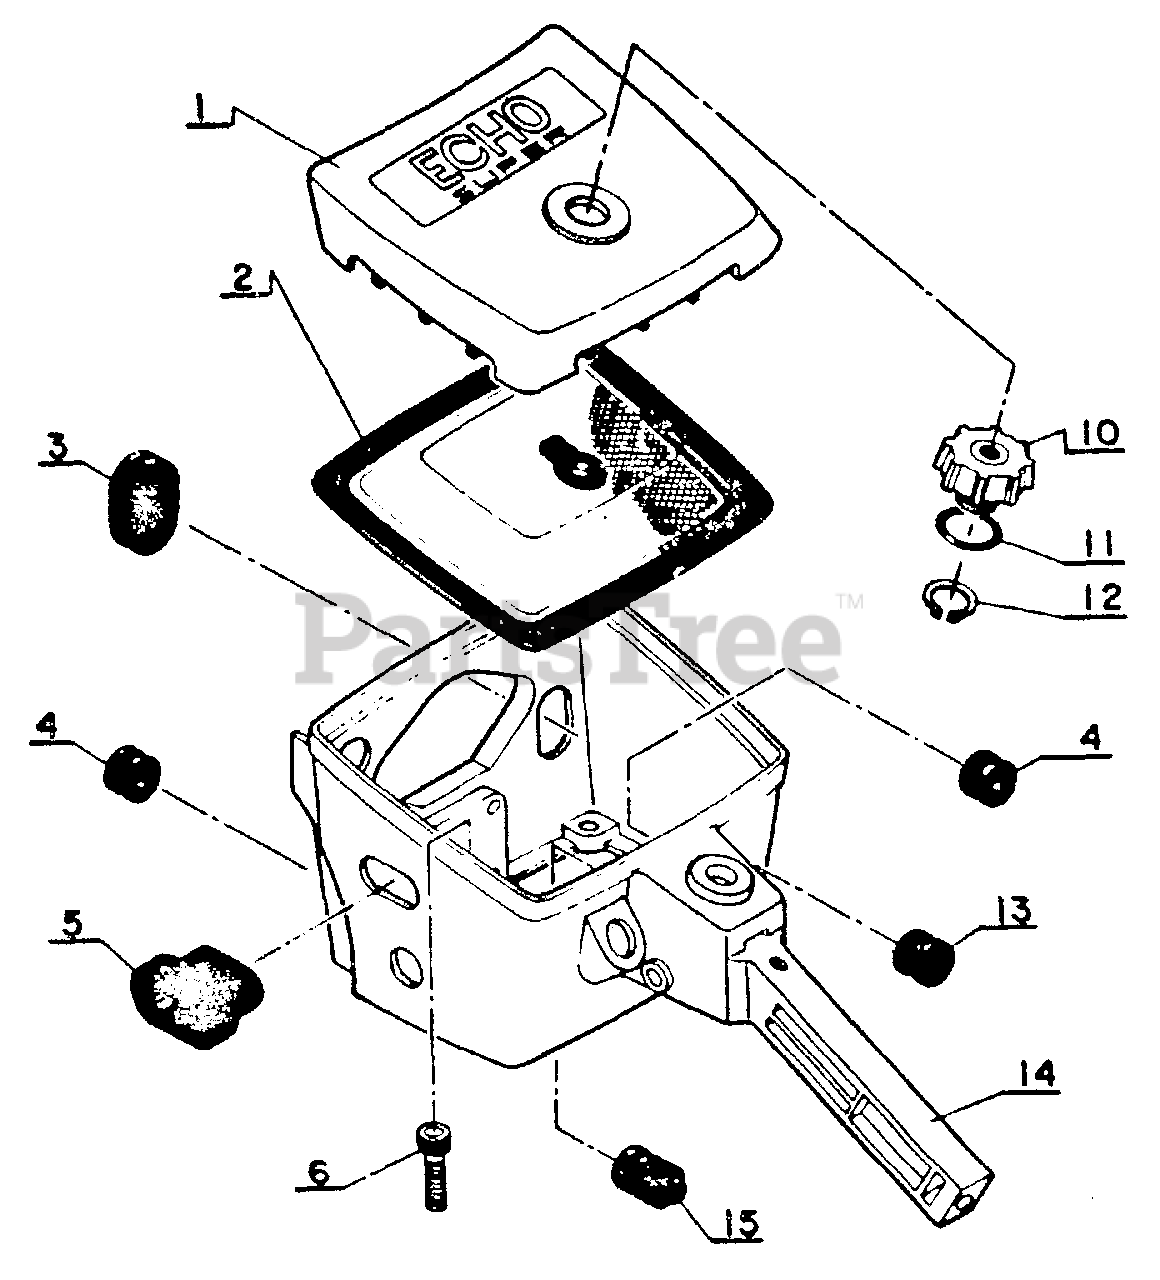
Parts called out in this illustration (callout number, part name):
1	COVER, AIR FILTER
2	FILTER, AIR
5	GROMMET
6	SCREW - 5X20
9	ECHO, name plate
11	O-RING - 14
12	RING, RETAINING - 11
14	HANDLE - RIGHT
